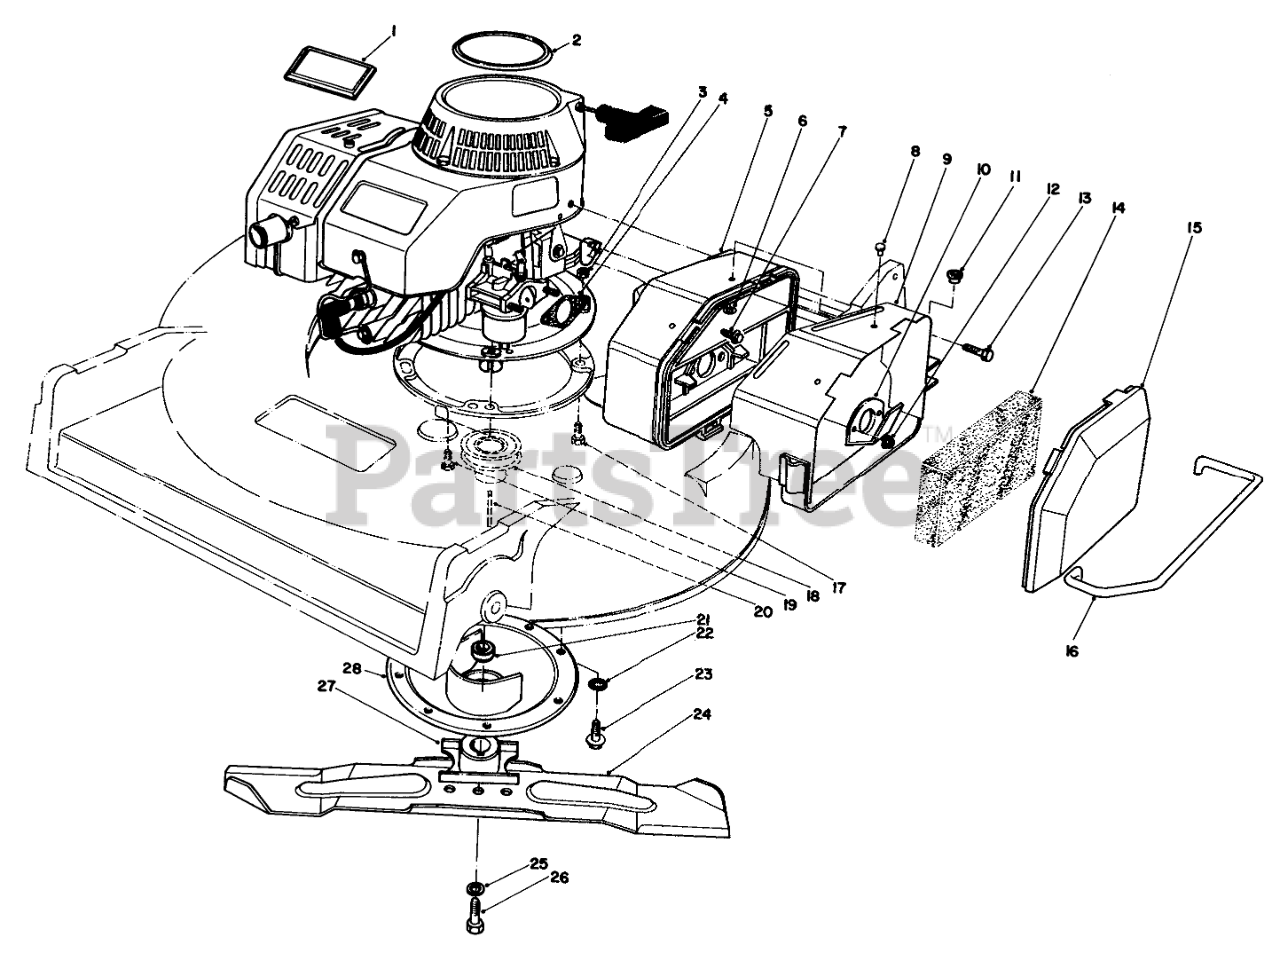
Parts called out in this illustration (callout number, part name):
1	Plate-Logo
2	Plate-Engine Logo
3	NUT-JAM
4	GASKET-AIR CLEANER
5	Air Cleaner Assembly (Incl. Ref. #6, 8 & 9)
6	WASHER-FLAT
7	HEX FL HD M.6X1.0X25MM
8	NUT-HEX
9	AIR CLEANER COVER WA
10	SPIT BACK DEFLECTOR
11	5/16 ID BSHG
12	NUT-LOCK
13	SCREW-HHF
14	FILTER
15	AIR CLEANER COVER
16	AIR CLEANER GUARD
17	SCREW-HH
18	PULLEY-DRIVER
19	SCREW-HH
20	KEY-SQUARE
21	SPACER-BLADE RETAINER
22	WASHER-LOCK, INTERNAL
23	SCREW-HWHTF
24	BLADE-21in
25	WASHER-LOCK
26	SCREW-BLADE
27	RETAINER-BLADE
28	Crankshaft Protector Assy.
